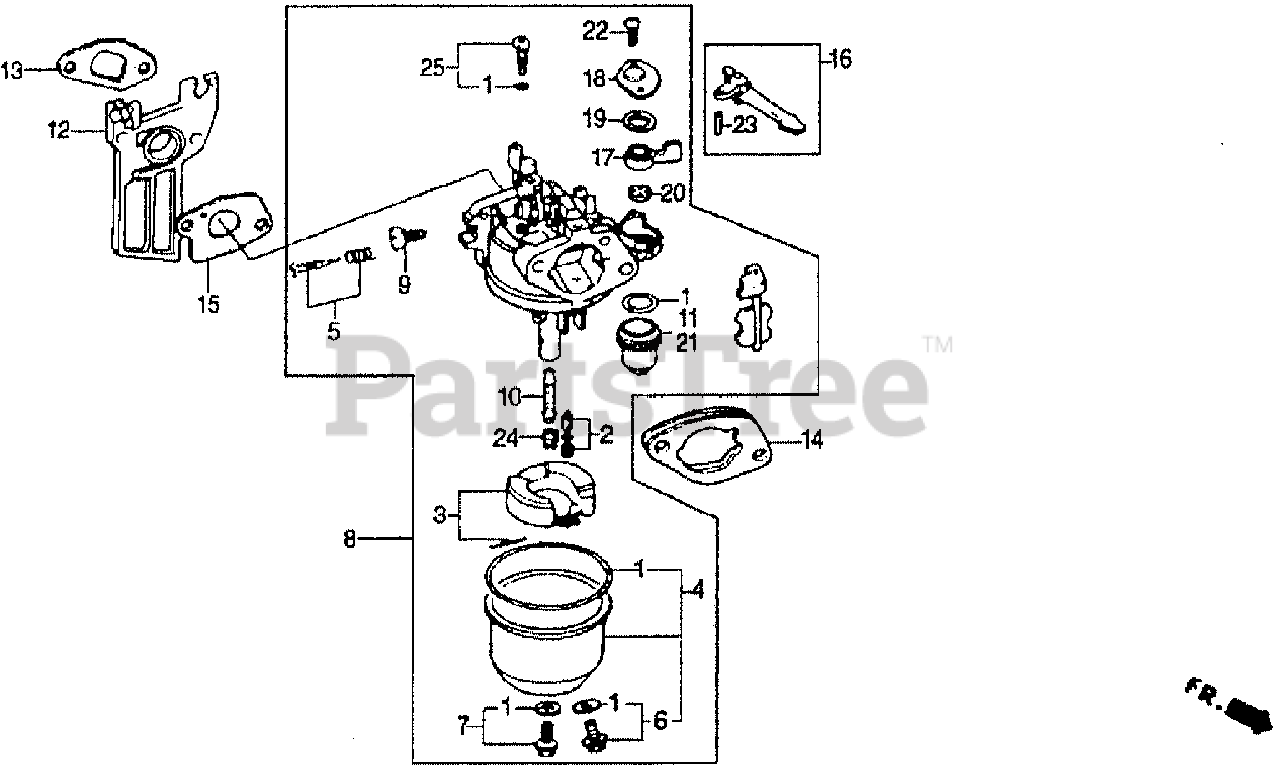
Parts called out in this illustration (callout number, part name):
1	GASKET SET
2	VALVE SET, FLOAT
4	CHAMBER SET, FLOAT
5	SCREW SET, PILOT
6	SCREW SET, DRAIN
7	SCREW SET B
8	CARBURETOR ASSY. (BE65B B)
8	CARBURETOR ASSY.
9	SCREW, THROTTLE STOP
10	NOZZLE, MAIN
11	GASKET, FUEL STRAINER CUP
12	INSULATOR, CARBURETOR
13	GASKET, INSULATOR
14	SPACER, CARBURETOR
15	GASKET, CARBURETOR
16	LEVER, CHOKE (STD)
17	LEVER, VALVE
18	PLATE, LEVER SETTING
19	SPRING, VALVE LEVER
20	GASKET, VALVE
21	CUP, FUEL STRAINER
22	SCREW, PAN (3X8)
23	PIN, SPRING (2X12)
24	JET, MAIN (#68)
24	JET, MAIN (#70)
24	JET, MAIN (#72)
25	JET SET, PILOT (#38)
